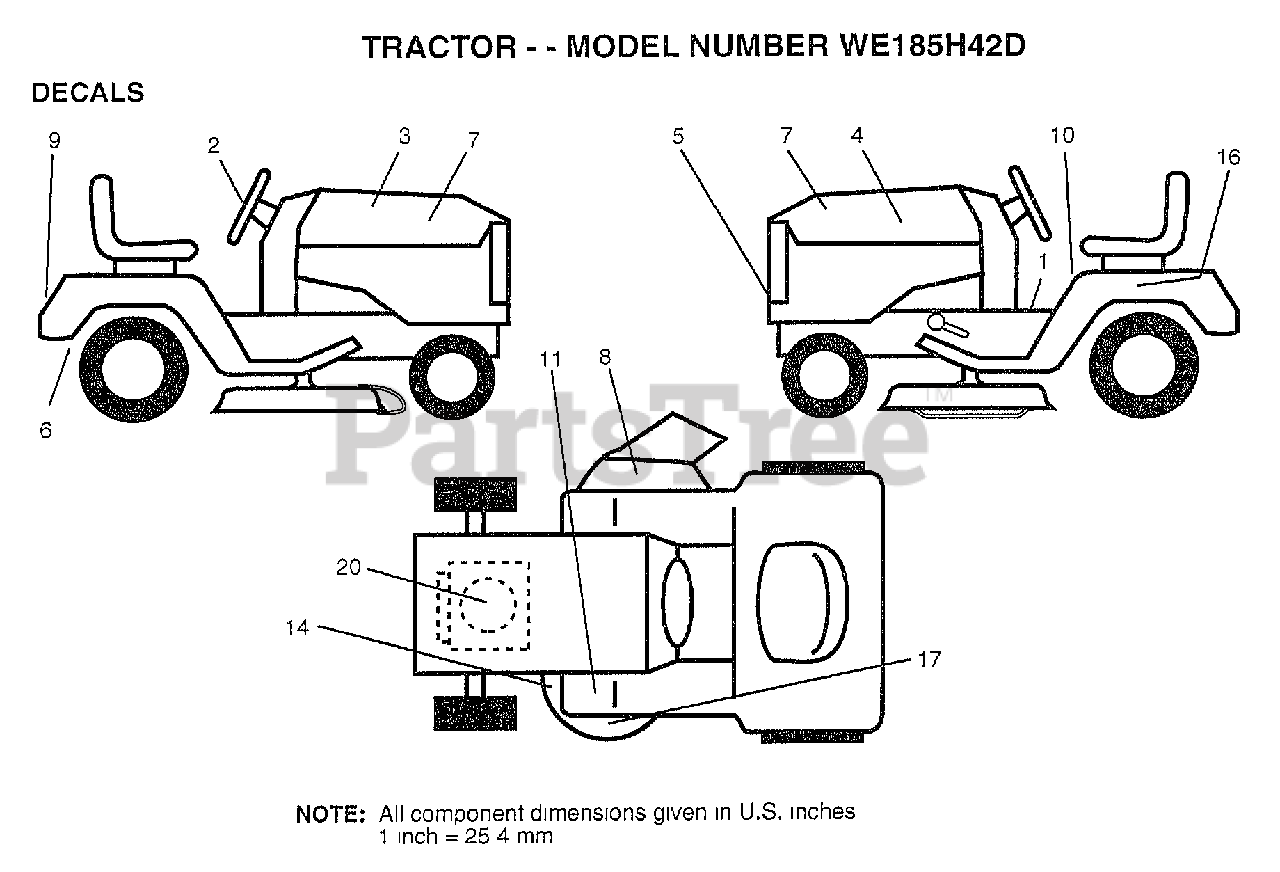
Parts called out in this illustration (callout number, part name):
1	DECAL SADDLE OPER
2	DECAL, INS STRG WH
3	DECAL.HOOD.RH.
4	DECAL.HOOD.LH
5	DECAL, GRILLE LENS
6	DECAL DRAWBAR LH
7	DECAL.PANEL.SIDE
8	"DECAL, WARNING"
9	DECAL.FENDER.LOGO
10	DECAL.CAUT.ENG/FR
11	DECAL T
14	"DECAL-SCHEM,BELT"
16	DECAL.BATRY.3-3908
17	DECAL, DECK GRASSEATER
20	DECAL, HP, ENGINE
